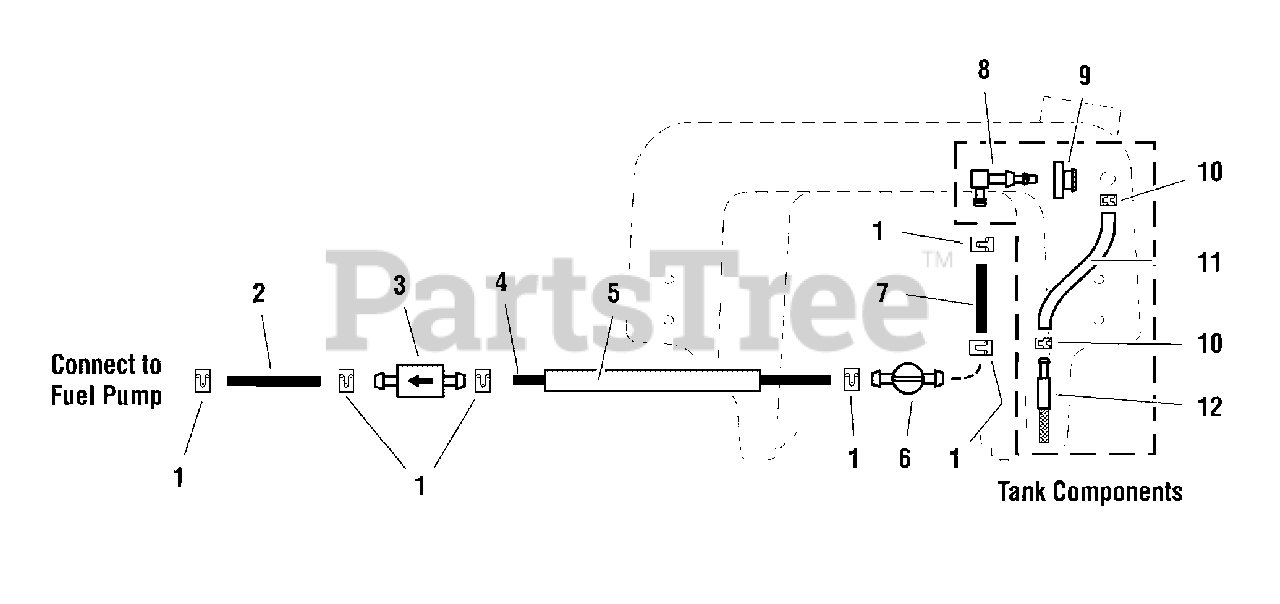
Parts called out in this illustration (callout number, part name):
1	CLAMP, HOSE, EXTERNAL, 1/2 - RED
2	HOSE, 1/4" FUEL, 7.00"
3	FUEL FILTER
4	HOSE, 1/4" FUEL, 35.00"
5	WIRE LOOM, 1/2" ID, 23" LONG
6	VALVE, FUEL SHUT OFF
7	HOSE, 1/4" FUEL, 5.00"
8	ELBOW FITTING
9	BUSHING-FUEL TANK RED RUBBER
10	HOSE CLAMP
11	HOSE, 20"
12	SCREEN FITTING
